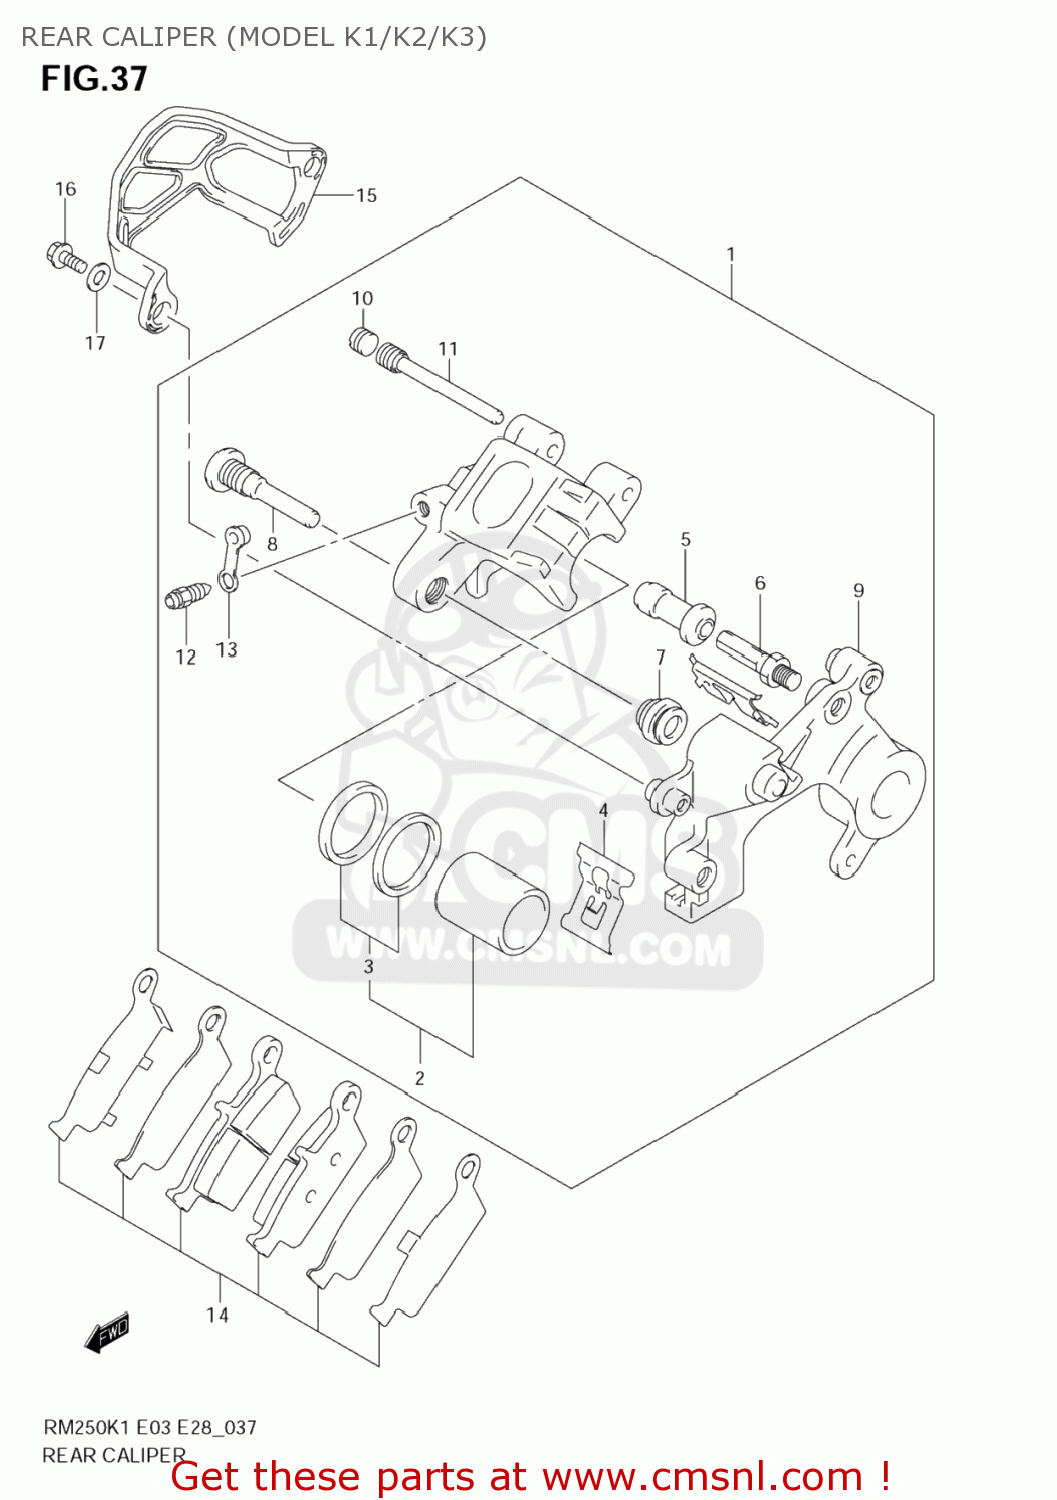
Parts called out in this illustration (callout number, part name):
1	CALIPER ASSY,RR
2	PISTON SET
3	SEAL SET,PISTON
4	SPRING,PAD
5	BOOT
6	BOLT
7	BOOT
8	PIN,BOLT
9	BRACKET
10	PLUG,PIN
11	PIN,HANGER
12	BLEEDER
13	CAP,BLEEDER
14	PAD & RETAINER SET
15	GUARD,RR CALIPER
16	BOLT
17	WASHER
